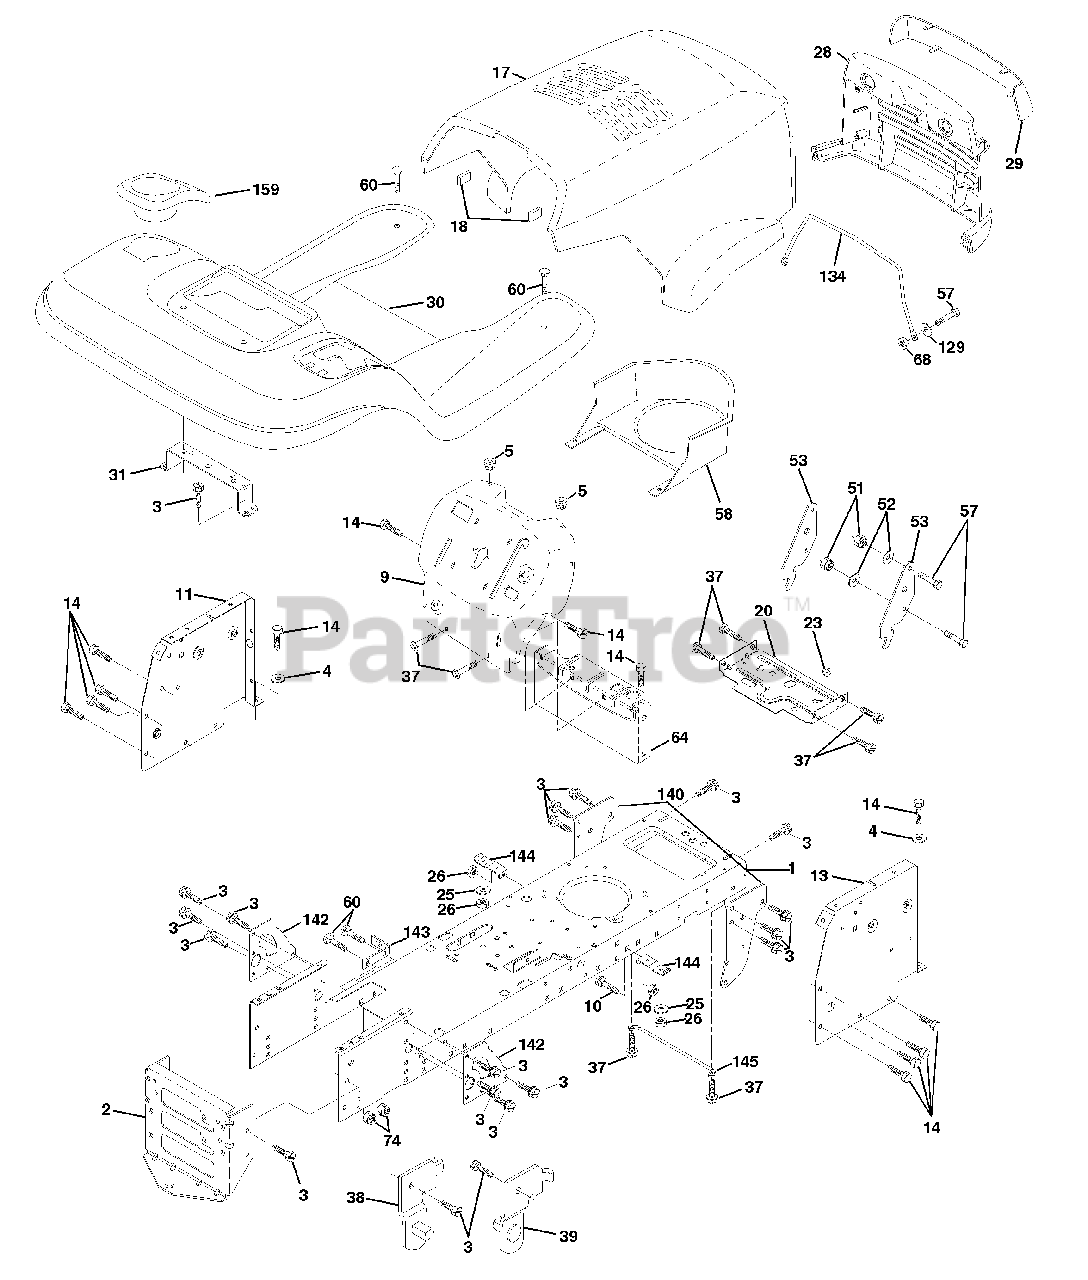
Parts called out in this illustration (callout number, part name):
1	Chassis Weldment
2	Drawbar, Stretch
3	Screw Thdrol 3/8-16x3/4 Ty-tt
4	Washer 13/32 x 3/4 x 16 Ga.
5	Bumper Hood/Dash
9	Dash P/L M, N/AMM N/HM
10	Bolt Carriage 3/8-16 x 1
11	Panel Dash Lh
13	Panel Dash Rh
14	Screw Thdrol 3/8-16x1/2 Ty-tt
17	Hood LT/PL Husqvarna
18	Bumper Hood
20	Plate Mtg Battery Fuel Tank Fr
25	Washer 13/32 X 13/16 X 12 Ga
26	Nut Lock Hex W/Ins 3/8-16 Unc
28	Grille LT/PL Husqvarna
29	Lens LT/PL Husqvarna
30	Fender Footrest STLT Pnt
31	Bracket Support Fender
37	Screw Thdrol 6/16-18 x 1/2 TYT
38	Bracket, Asm. Pivot, L.H., Mower Rear
39	Bracket, Asm. Pivot, R.H., Mower Rear
51	Nut Lock Hex W/Ins 1/4-20
52	Washer 9/32 x 7/8 x 16 Ga.
53	Bracket Pnt. Pick off LT/PL Husqvarna
57	Bolt Hex 1/4-20 x 3/4
58	Air Duct Engine P/L
60	Bolt Rdhd Sqnk 3/8-16unc x 3/4
64	Dash Lower STLT
68	Nut Keps Hex 1/4-20unc
74	Nut Crownlock 3/8-16 UNC
129	Washer 9/32 x 5/8 x 16 Ga.
134	Rod Support Hood LT/PL Husq.
140	Bracket Suspension Front
142	Plate Reinforcement STLT
143	Bracket Swaybar Chassis
144	Bracket Pnt Footrest STLT
145	Rod Pivot Chassis/Hood
159	Cupholder Stlt Grey
